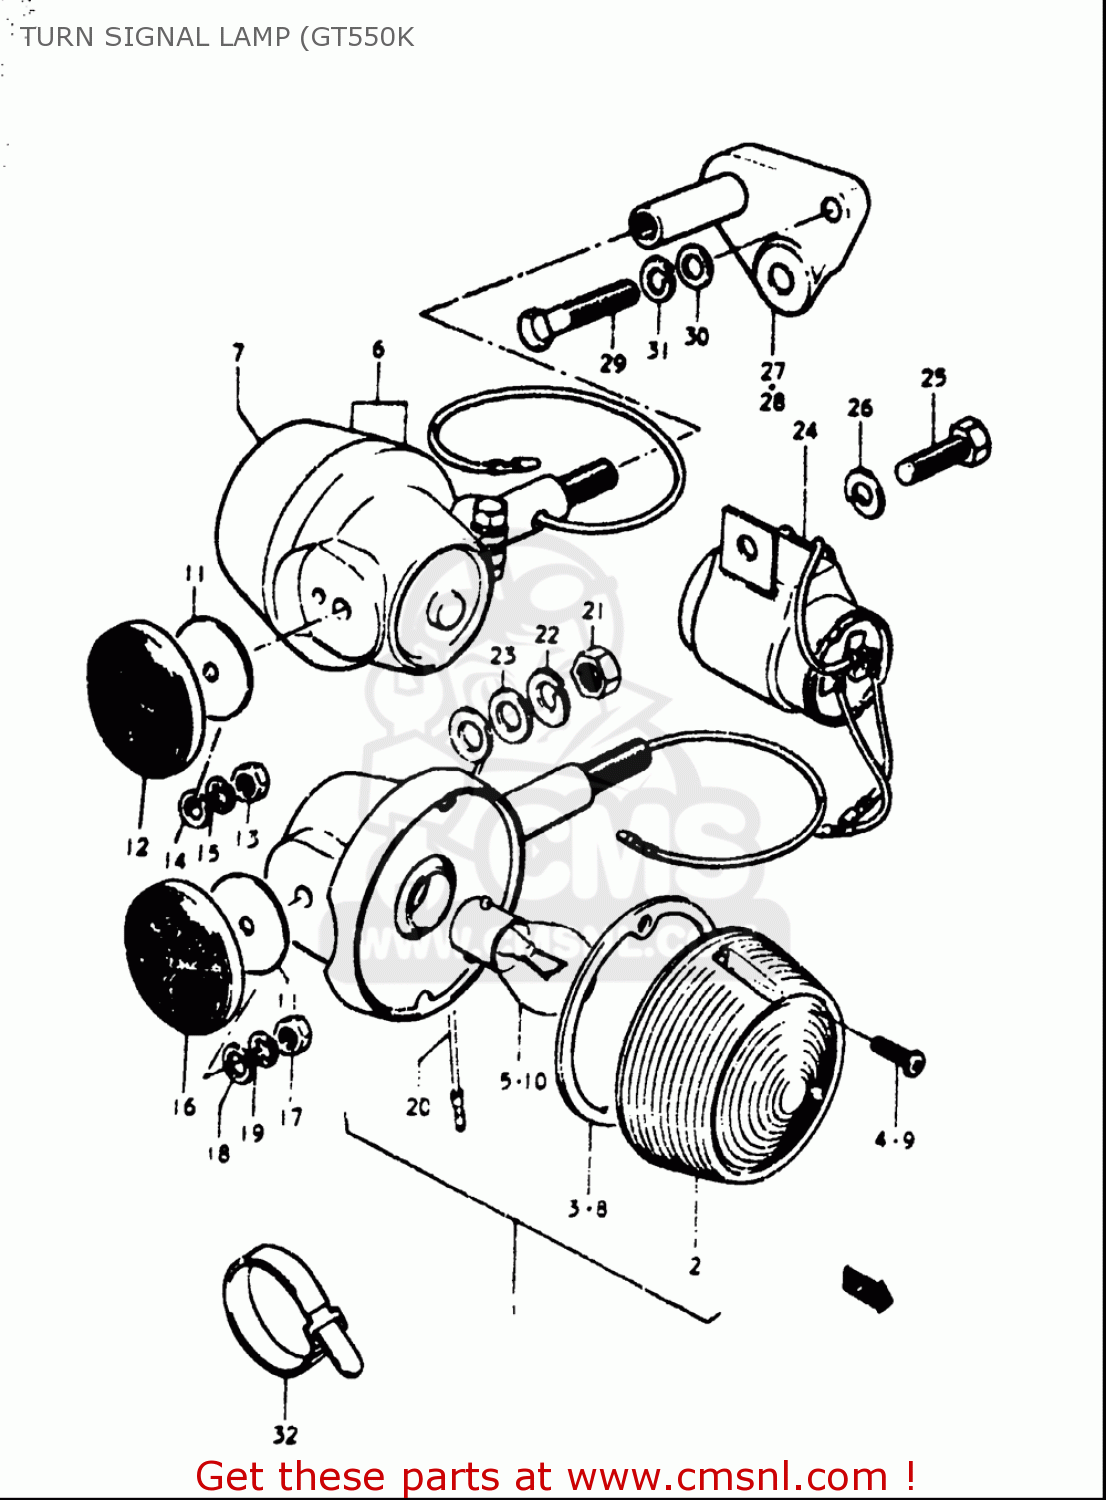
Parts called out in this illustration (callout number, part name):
2	LENS
3	GASKET,TURNSIGNAL LENS (NAS)
4	SCREW
5	BULB(12V23W,STANLEY,A4577A)
7	LENS
8	GASKET,TURNSIGNAL LENS (NAS)
9	SCREW
10	BULB(12V23W,STANLEY,A4577A)
13	NUT
14	WASHER(5.5X18X1)
15	WASHER,LOCK
16	REFLEX REFLECTOR,RR
17	NUT
18	WASHER(5.5X18X1)
19	WASHER,LOCK
20	LEAD WIRE,EARTH
21	NUT
22	WASHER,LOCK
23	WASHER
24	RELAY,TURN SIGNAL
25	BOLT
26	WASHER,LOCK
27	BRACKET, REAR TURN SIGNAL RH
29	BOLT
30	WASHER
31	WASHER,LOCK
32	CLAMP
